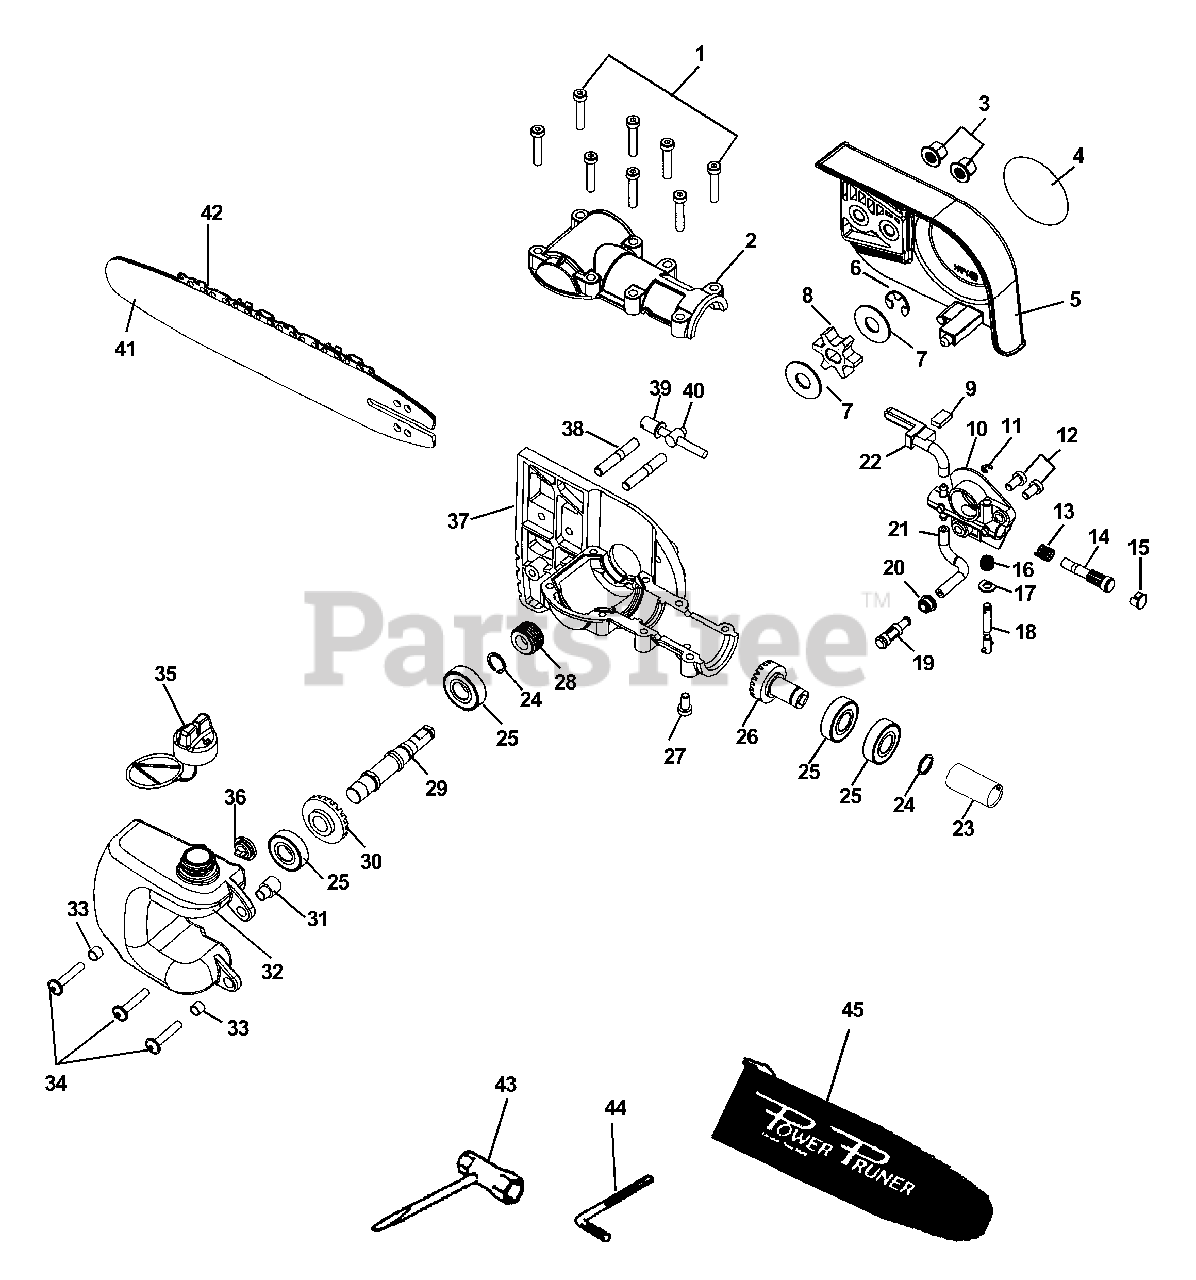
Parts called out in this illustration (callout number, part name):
1	SCREW - 5X25
2	CASE, GEAR - UPPER
3	NUT - 6 -- FLANGE
4	LABEL - ECHO
5	GUARD, SPROCKET
6	RING, RETAINING
8	SPROCKET, DRIVE
9	PAD, FOAM
10	AUTO-OILER ASSY
11	RING, RETAINING
12	SCREW - 5X10
13	SPRING, PLUNGER
14	PLUNGER ASSY
15	CAP, OIL PUMP
18	NEEDLE, ADJUST
19	FILTER, OIL
20	GROMMET
21	PIPE - 3X6X75 -- BLACK
22	PIPE, OIL OUTLET
23	COLLAR - 22
24	RING, RETAINING - 12
25	BEARING, BALL - 6001
26	GEAR - BEVEL
27	SCREW - 5X10
28	GEAR - WORM
29	GEAR - SHAFT
30	GEAR - BEVEL
32	TANK, OIL
34	SCREW - 5X20
35	CAP ASSY
37	CASE, GEAR - LOWER
38	STUD - 6
39	SCREW, TENSIONER
40	TENSIONER, CHAIN
41	GUIDE BAR - 10" (25cm)
41	GUIDE BAR - 10" (25cm) Intenz
42	SAW CHAIN - 10" (25cm)
43	T-WRENCH - 10X19mm
44	HEX KEY - 3mm
45	COVER, GUIDE BAR
